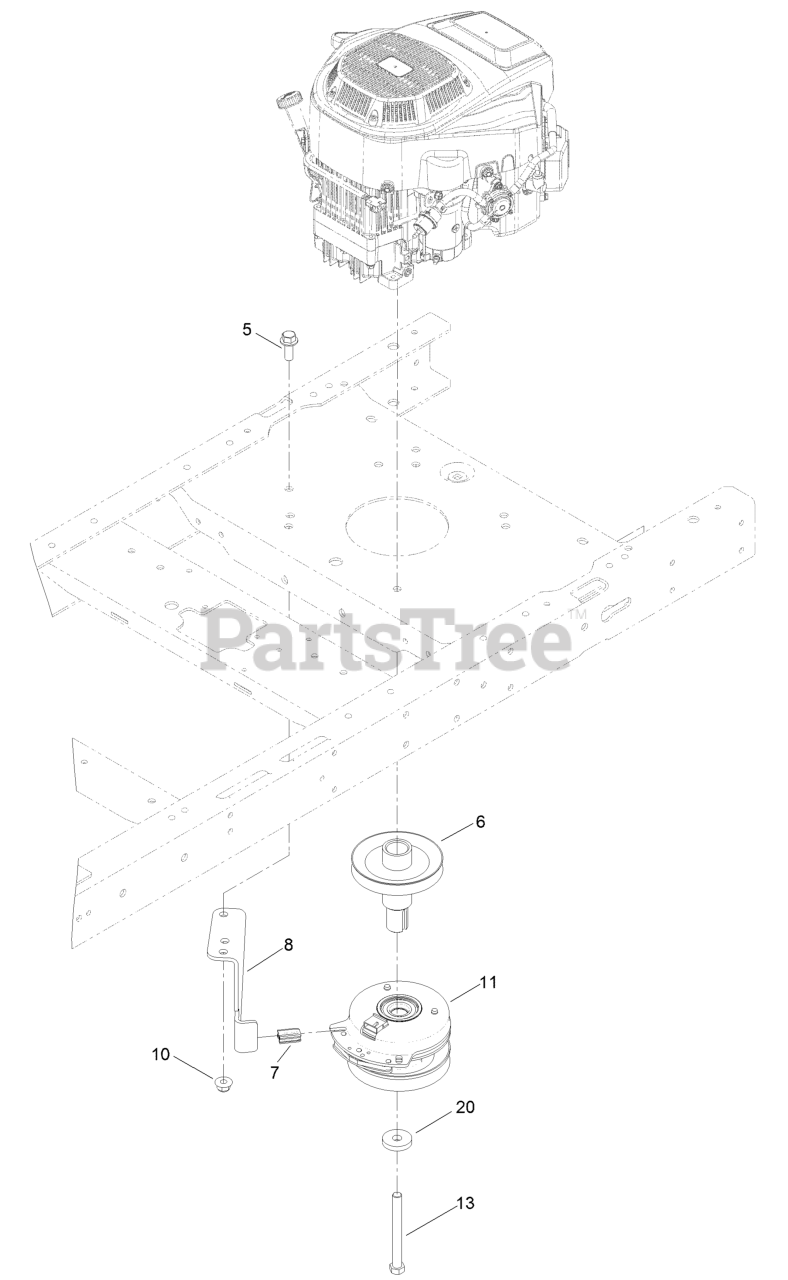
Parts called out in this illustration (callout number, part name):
5	SCREW-HHF 3/8-16 X 1
6	PULLEY-ENGINE
7	ISOLATOR-CLUTCH
8	STOP-CLUTCH
10	NUT-HF, NI
11	CLUTCH-PTO
13	SCREW-HH
20	WASHER
